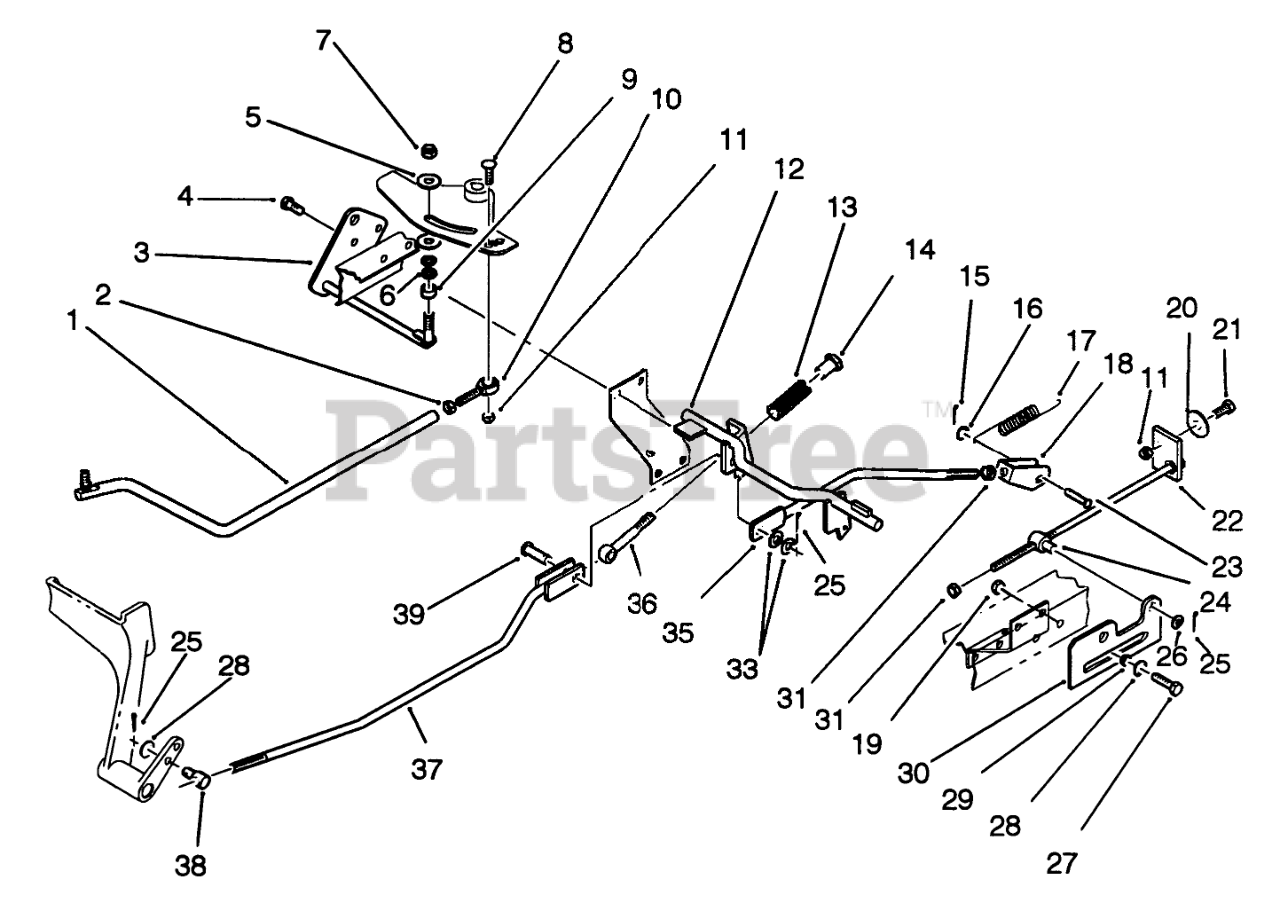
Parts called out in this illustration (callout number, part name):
1	ROD-CONTROL R
2	Nut
3	WLDMT-ROD R
4	Screw
5	FRICTION WASHER
6	WASHER-SPRING DISC
7	NUT
8	Bolt-Carriage
9	SPACER
10	BALL-END
11	NUT-LOCK, NI
12	WLDMT-NEUTRAL SHA R
13	SPRING-COMPRESSION
14	NUT-RETAINER
15	PIN-COTTER
16	WASHER-FLAT
17	SPRING-EXTENSION
18	WLDMT-CLEVIS
20	WASHER
21	SCREW-HH
22	WLDMT-BOLT
24	TRUNNION
25	PIN-COTTER
26	WASHER-PLAIN
27	SCREW-HH
28	WASHER-PLAIN
29	SPACER
30	PLATE R
31	NUT-JAM
33	Washer
34	Collar
35	WLDMT-ROD
36	EYE-BOLT
37	WLDMT-BRAKE ROD
38	TRUNNION
39	CLEVIS PIN
